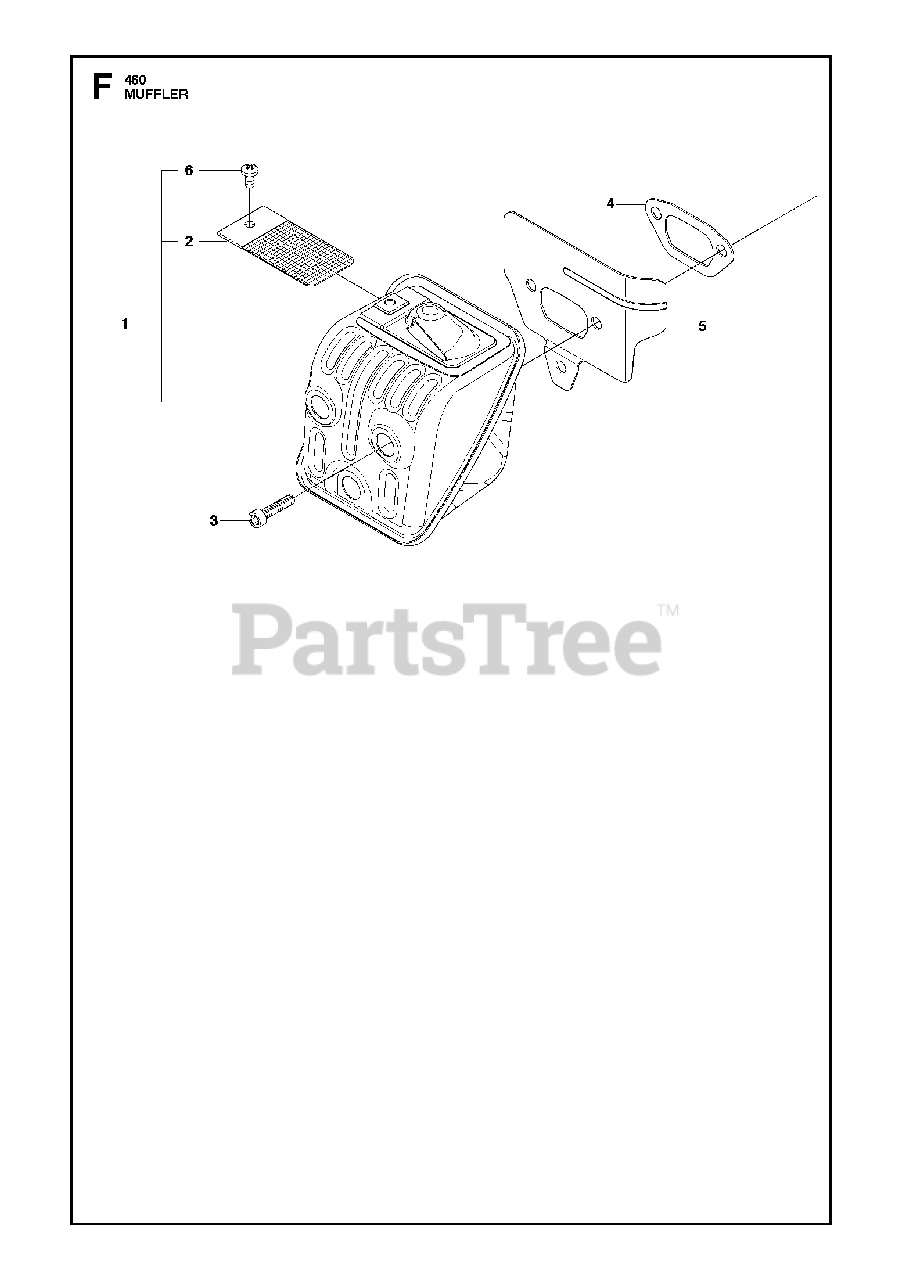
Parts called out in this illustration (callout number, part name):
1	MUFFLER ASSY
2	SPARK ARRESTOR SCREEN
3	SCREW MC6S 6X16
5	HEAT SHIELD
6	SCREW
